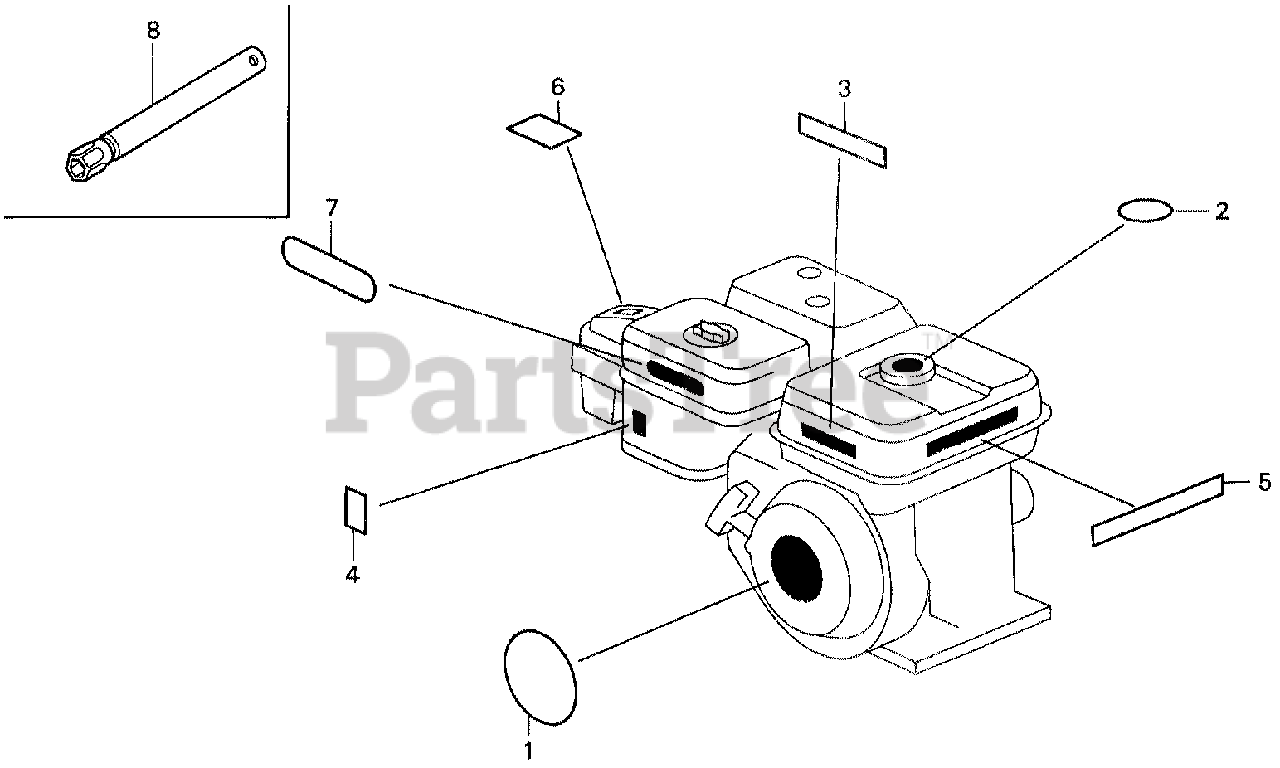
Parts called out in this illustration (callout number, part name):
1	EMBLEM
3	LABEL, CAUTION
4	MARK, CHOKE
8	WRENCH, SPARK PLUG
